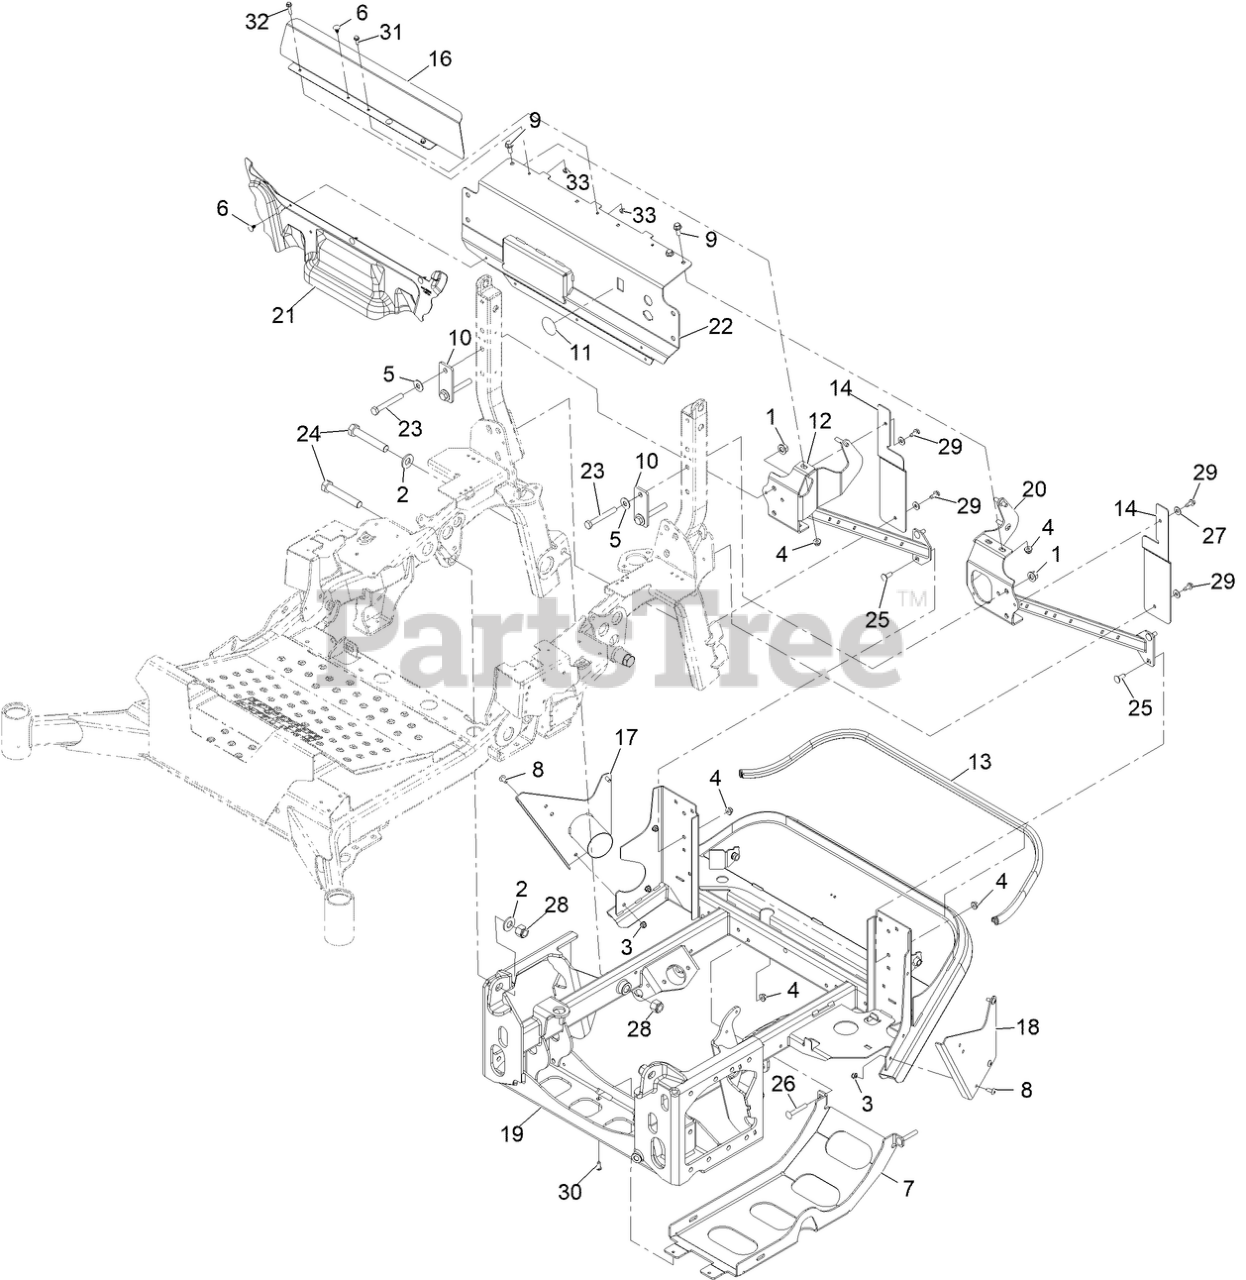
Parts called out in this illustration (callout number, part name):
1	NUT-LOCK
2	WASHER
3	NUT-HF, NI
4	NUT-HF, NI
5	WASHER-SPRING
6	PLUG-PLASTIC
7	PLATE-SKID
8	SCREW-TORX
9	SCREW-HHF
10	PLATE-SPACER
11	DECAL-COVER
12	WLDMT-ROPS RH BRACE
13	SEAL-BULB
14	SHEET-ROPS AIRDAM
16	SHIELD-AIR
17	PLATE-EXHAUST
18	PLATE-BATTERY COVER
19	FRAME, POWER [BLACK]
20	WLDMT-ROPS LH BRACE
21	PANEL-HEAT DEFLECTOR
22	CHANNEL-CROSS, ASM
23	SCREW-HH
24	SCREW-HH
25	SCREW-CARR
26	SCREW-CARR
27	WASHER-FLAT
28	NUT-LOCK, NI
29	SCREW-HWHTF
30	SCREW-BHTF
31	SCREW-HHF
32	SCREW-HHF
33	NUT-HF
